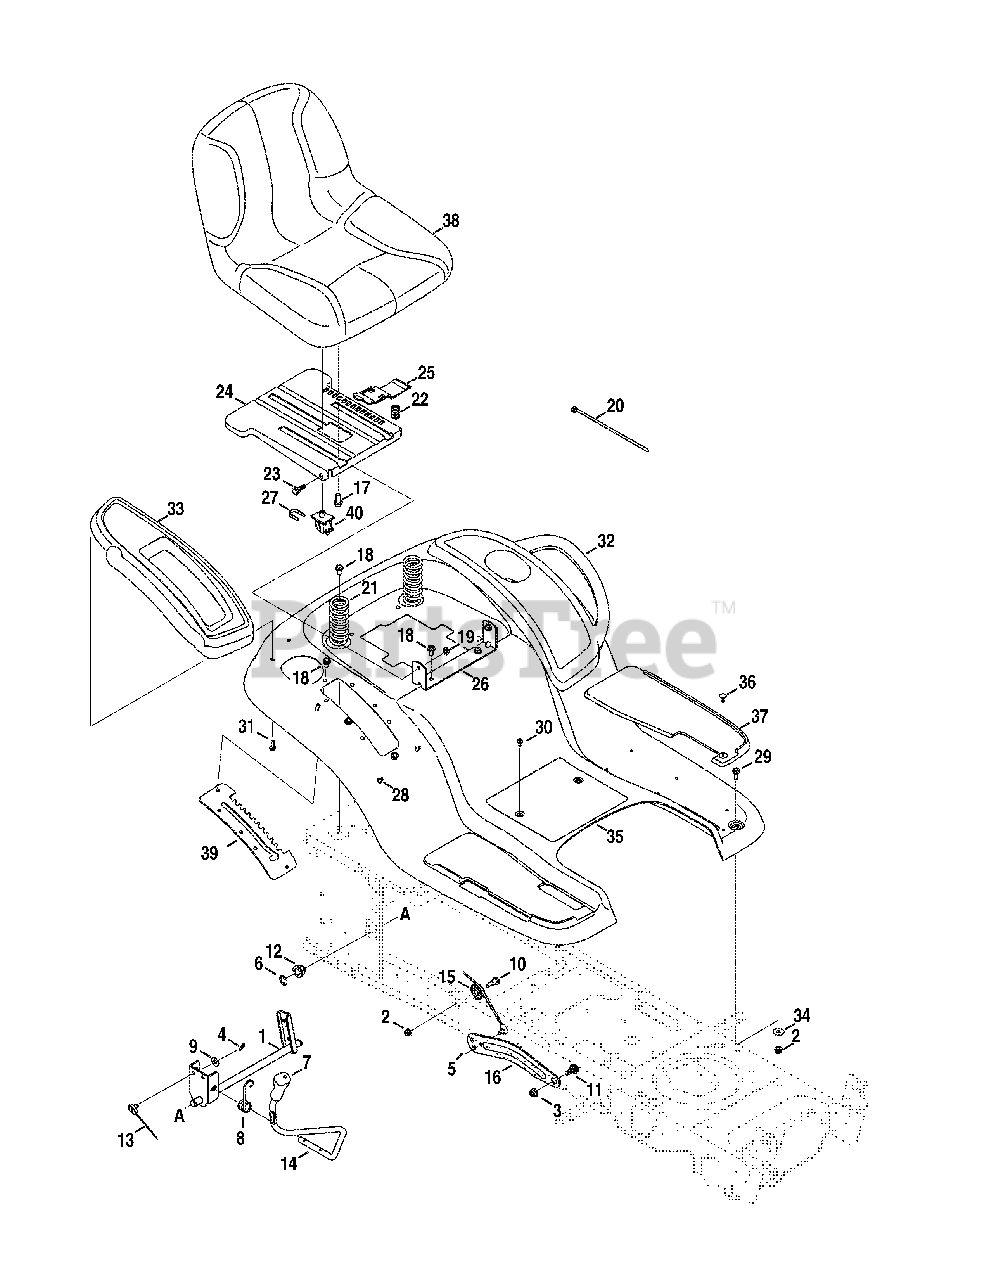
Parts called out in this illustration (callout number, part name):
1	Lift Shaft Assembly
2	Flangelock Nut, 5/16-18
3	Flangelock Nut, 3/8-16
4	Cotter Pin, .072 DIA. X 1.13 LG
5	Bow-Tie Cotter Pin
6	E-Ring, .625 DIA. SHAFT
7	Handle Grip
8	Torsion Spring
9	Spring Washer, .401 X .870 X .063
10	Shoulder Screw, .437 X .470:5/16-18
11	Shoulder Bolt, .625X.175:3/8-16
12	Hex Flange Bearing
13	Lift Cable, 16.16 LG
14	Lift Handle
15	Pulley Roller Cable
16	RH Lift Arm
16	LH Lift Arm
17	Hex Head Flange, 3/8-16:.875
18	Taptite Screw, Lock Washer, 5/16-18:.750
19	Flangelock Nut, 5/16-18
20	Cable Tie, 3/16 X .05 X 7.4
21	Compression Spring, 1.71 X 3.735 X .238
22	Compression Spring, .68 X 1.065 X .055
23	Shoulder Screw, .437 X .268:5/16-18
24	Seat Mounting Bracket
25	Seat Adjustment Lever
26	Seat Pivot Bracket
27	Switch Retainer Clip
28	Hi-Lo Screw, Lock Washer, 1/4-15:0.50
29	Carriage Bolt, 5/16-18:.750
30	Taptite Screw, Lock Washer, 1/4-20:0.500
31	Hi-Lo Screw, Lock Washer, 1/4-15:0.750
32	LH Fender Cover
33	RH Fender Cover
34	Flat Washer, .344 X 1.00 X .063 HDN
36	Ratchet Clip
37	LH Foot Pad
37	RH Foot Pad
38	Seat - Sears High Back
38	Arm Rest Kit - Sears High Back Pro
38	Armrest Kit - LH w/Hardware
38	Armrest Kit - RH w/Hardware
39	Lift Bracket
40	Seat Switch
